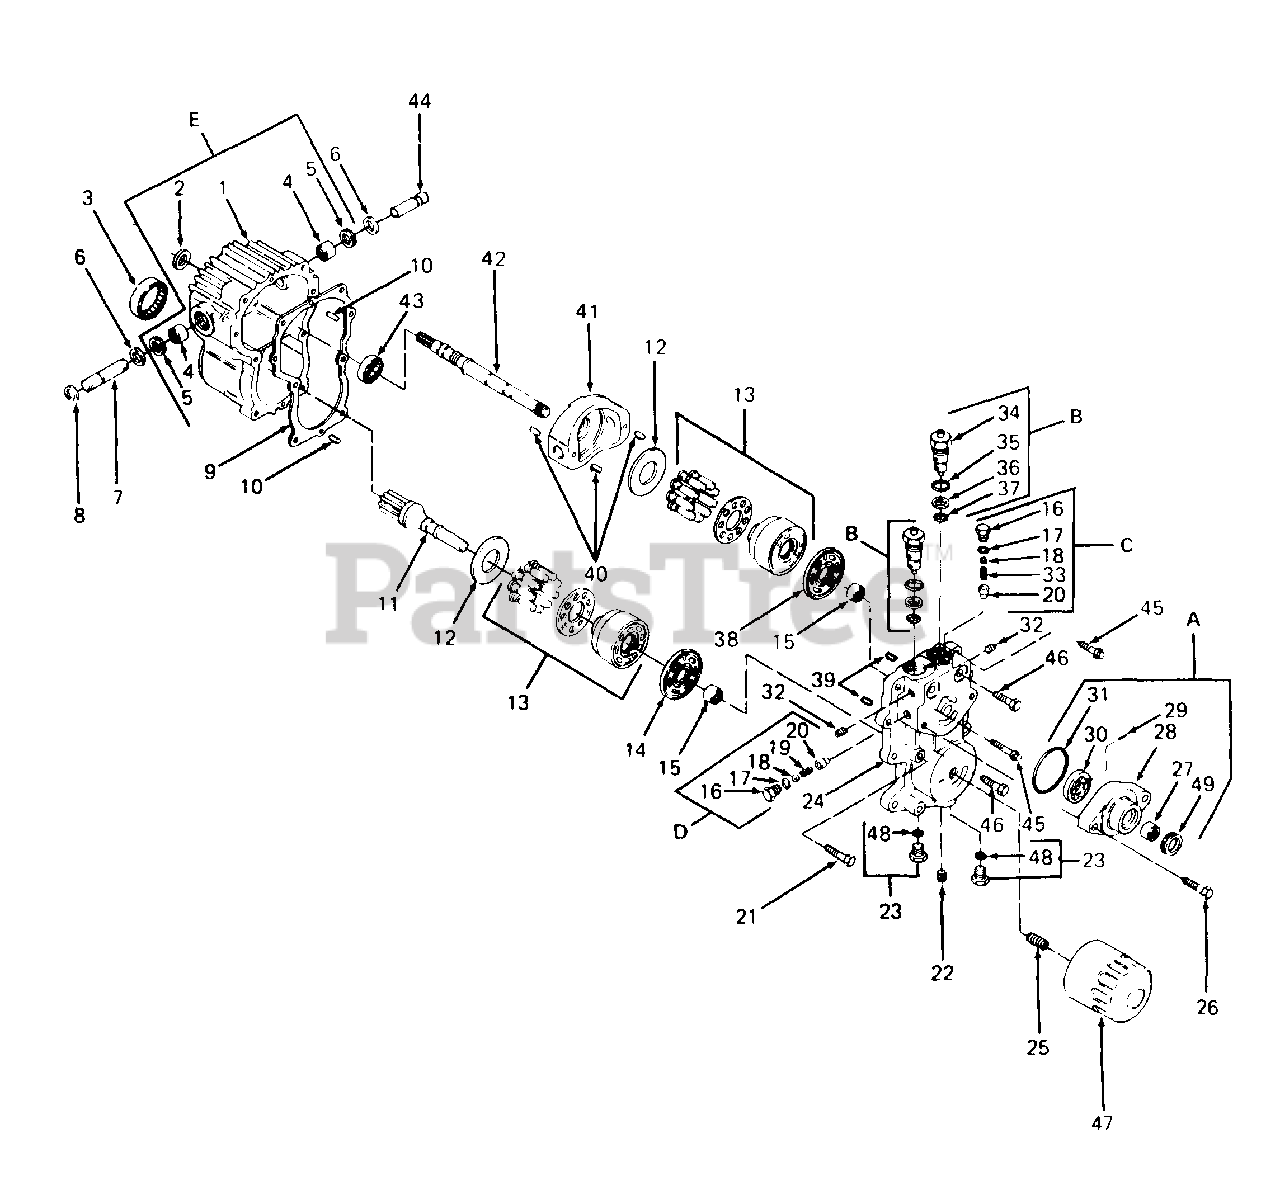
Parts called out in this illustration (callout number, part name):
1	Housing, Transmission
2	Seal, Lip
3	Bearing, Roller
4	Bearing, Needle
5	Seal, Lip
7	Shaft, Trunnion
8	Ring, Retaining
9	Gasket
10	Pin
11	Shaft, Motor
12	Plate, Thrust
13	Block, Cylinder
14	Plate, Valve
15	Bearing, Roller
16	Plug
17	O-Ring
18	Kit, Shim Pack
19	Spring, Center Relief Valve
20	Cone, Relief Valve
24	Center Section
27	Bearing, Needle
28	Charge Pump Housing
30	Gerotor
33	Spring, Implement Relief
34	Valve
36	Ring, Back-up
38	Plate, Valve
42	Shaft, Pump
44	Shaft Assembly, Trunnion
45	Screw, 12 Point
47	Oil Filter
49	Seal, Lip
A	Kit, Charge Pump
B	Valve Assembly
C	Kit, Relief Valve
D	Kit, Relief Valve
E	Housing Assembly
